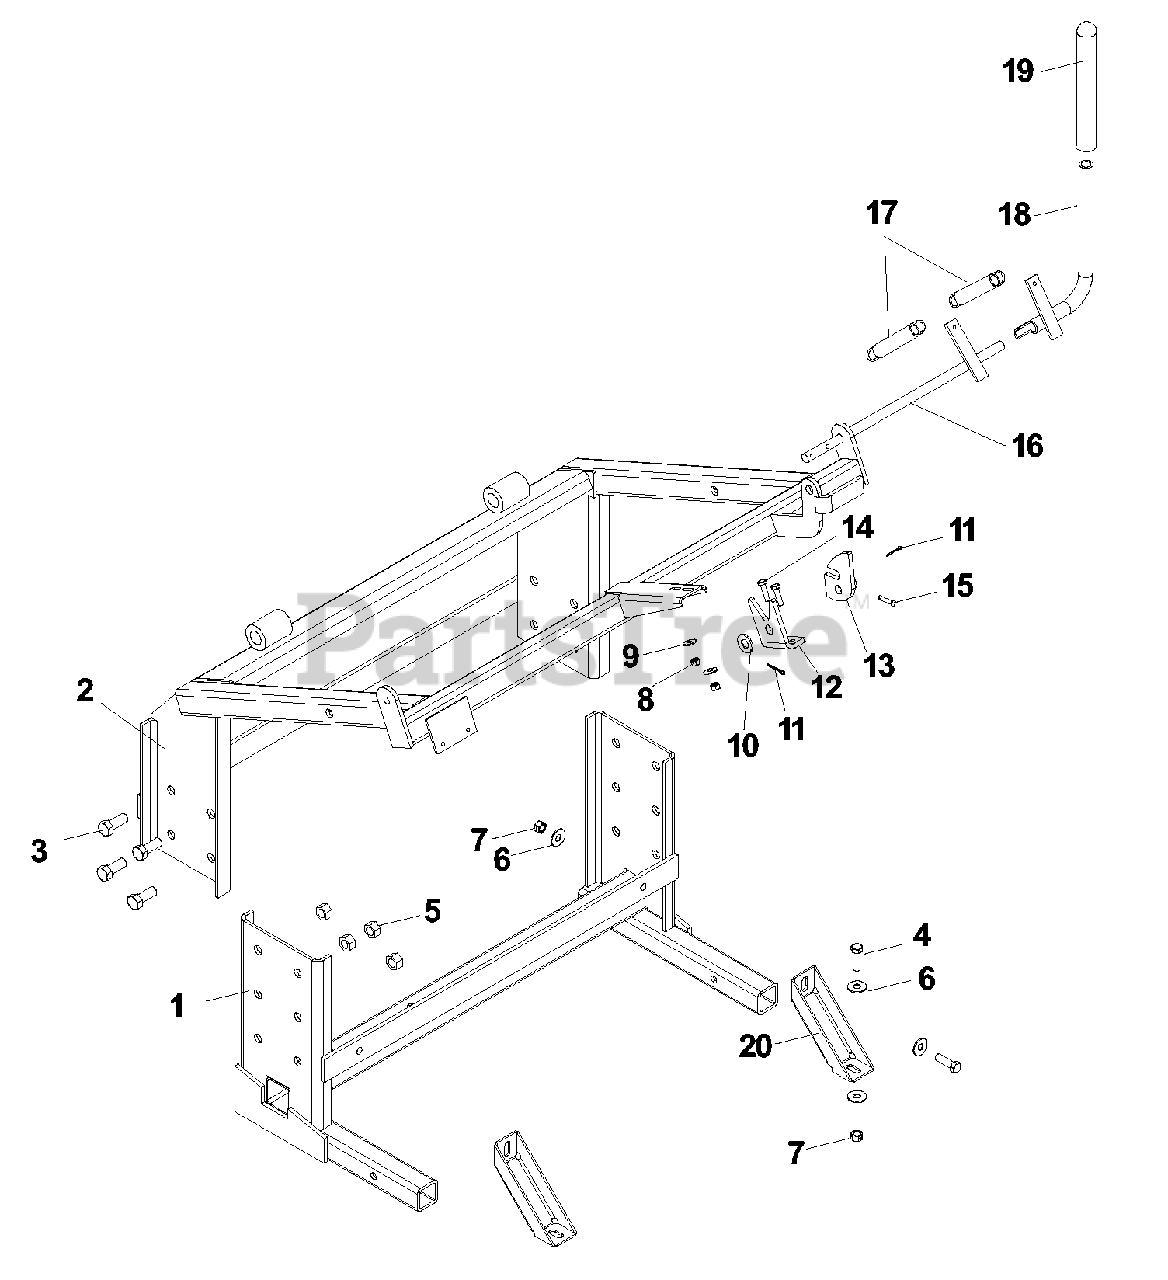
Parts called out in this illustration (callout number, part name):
1	LOWER FRAME
2	UPPER FRAME
3	BOLT, 1/2-13 X 1 1/4
4	BOLT, 3/8-16 X 1 1/4
5	NUT, 1/2-13, NYLOC
6	WASHER, 3/8
7	NUT, 3/8-16, NYLOC
8	NUT, 1/4-20, NYLOC
9	WASHER, 1/4
10	WASHER, 1/2
11	PIN, COTTER, 3/32 X 3/4
12	LATCH BASE
13	LATCH CATCH
14	BOLT, 1/4-20 X 1
15	PIN, CLEVIS, 3/16 X 1
17	SPRING
18	LATCH HANDLE
19	HANDLE GRIP
20	HITCH BRACKET
